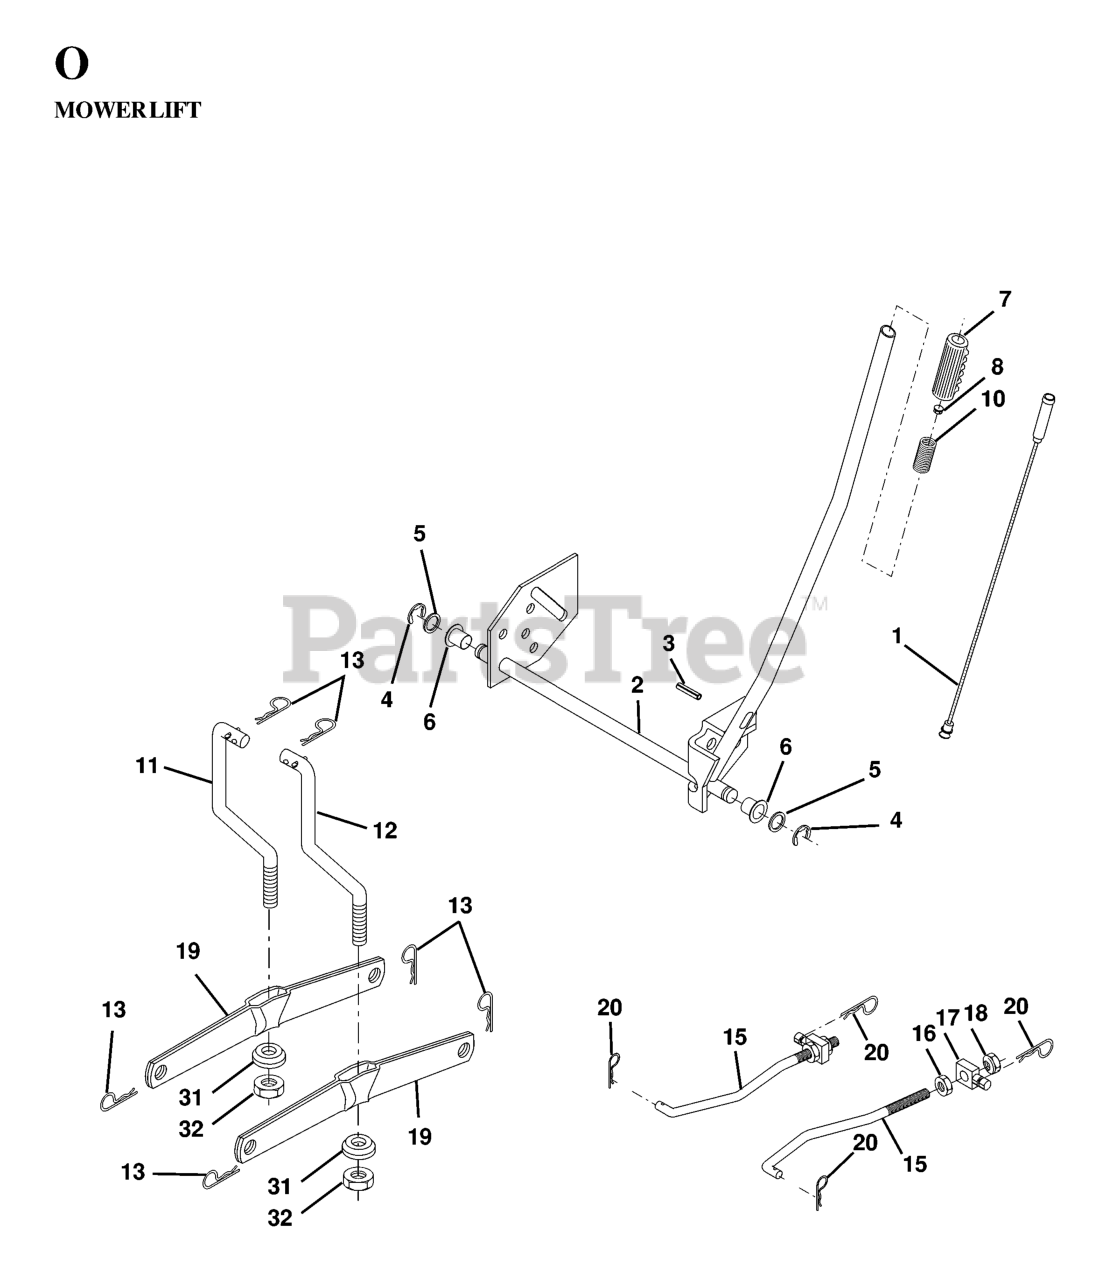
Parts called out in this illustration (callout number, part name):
1	WIRE.INNER.HANDLE.LIFT.LEVER
2	SHAFT ARM LIFT RH
3	PIN GROOVE.
4	RETAINING RING LT
6	BEARING.NYLON
7	GRIP HANDLE
8	PLUNGER BUT KIT
10	SPRING, COMP T
11	LINK LIFT LH
12	LINK LIFT RH
13	RETAINER-SPRNG RB
15	FRONT LINK
16	NUT.HEX.JAM.1/2-13
17	TRUNION
18	NUT.LK.W/WSH.1/2.
19	ARM.REAR.SUSPENSION
20	SPRING RETAINER
31	BEARING PIVOT
32	NUT CROWNLOCK 3/8-24
